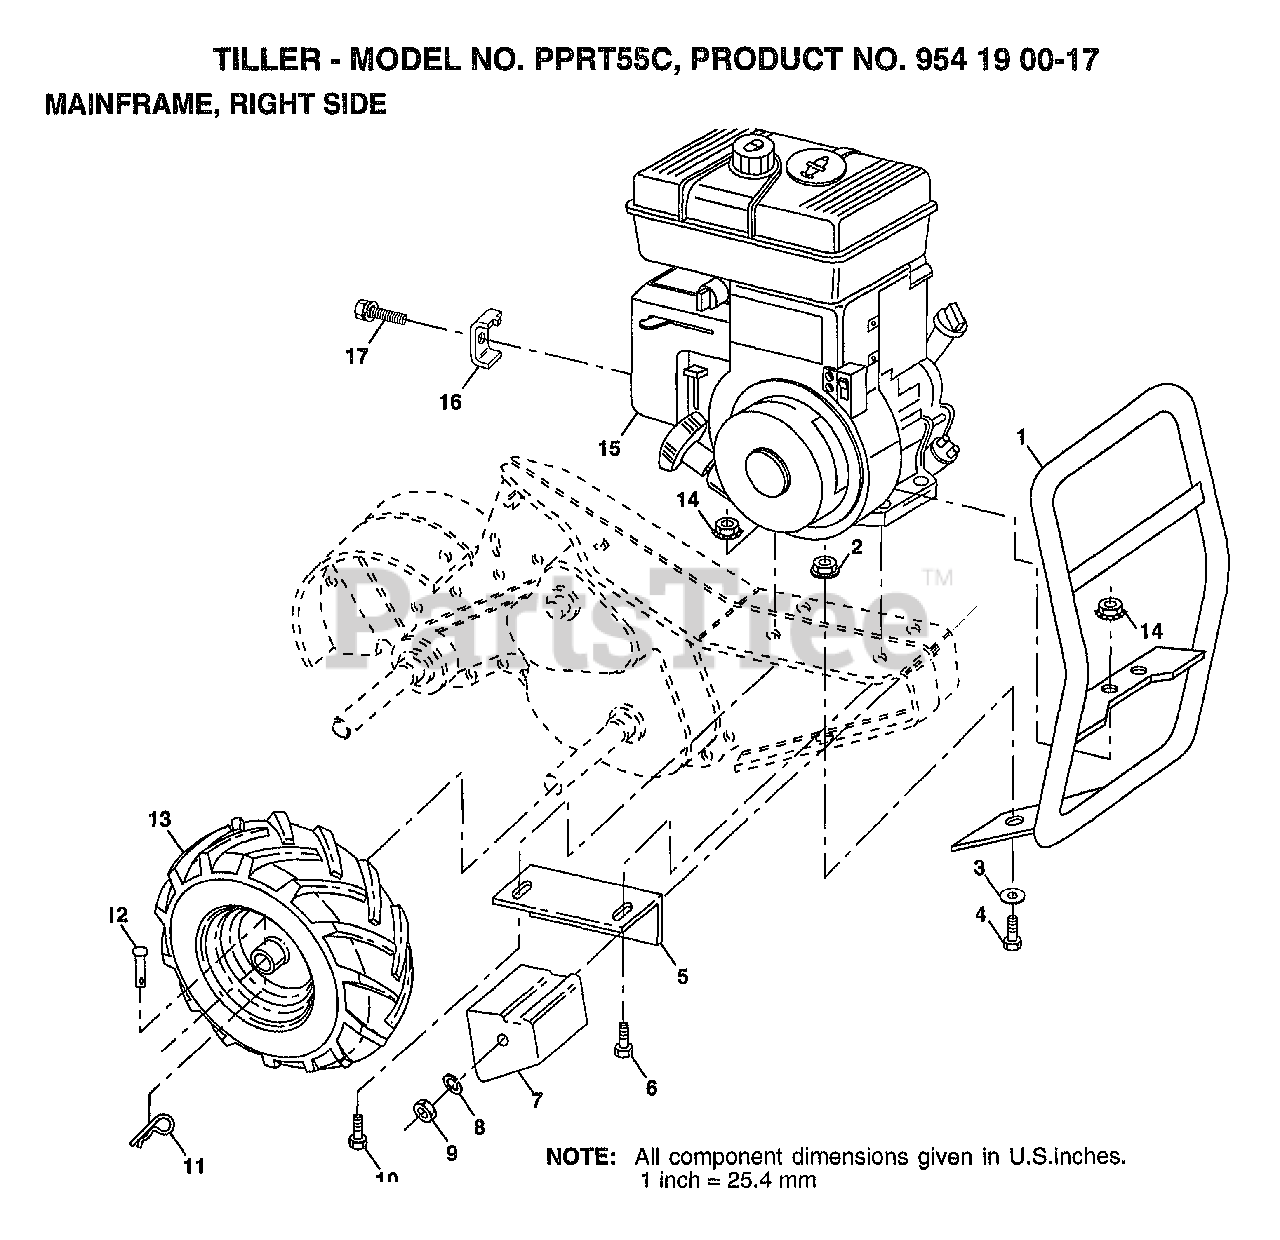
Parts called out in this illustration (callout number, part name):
1	BUMPER
2	LOCKNUT TI
3	WASHER
4	BOLT
5	BRACKET RH CRT
6	BOLT
7	COUNTERWEIGHT CRT
8	LOCKWASHER
9	NUT.HEX.3/8-16UNC
10	BOLT.HEX.5/16-1.5
11	RETAINER M
12	RIVET DRILLED
13	TIRE TI
16	CLAMP
17	SCREW
